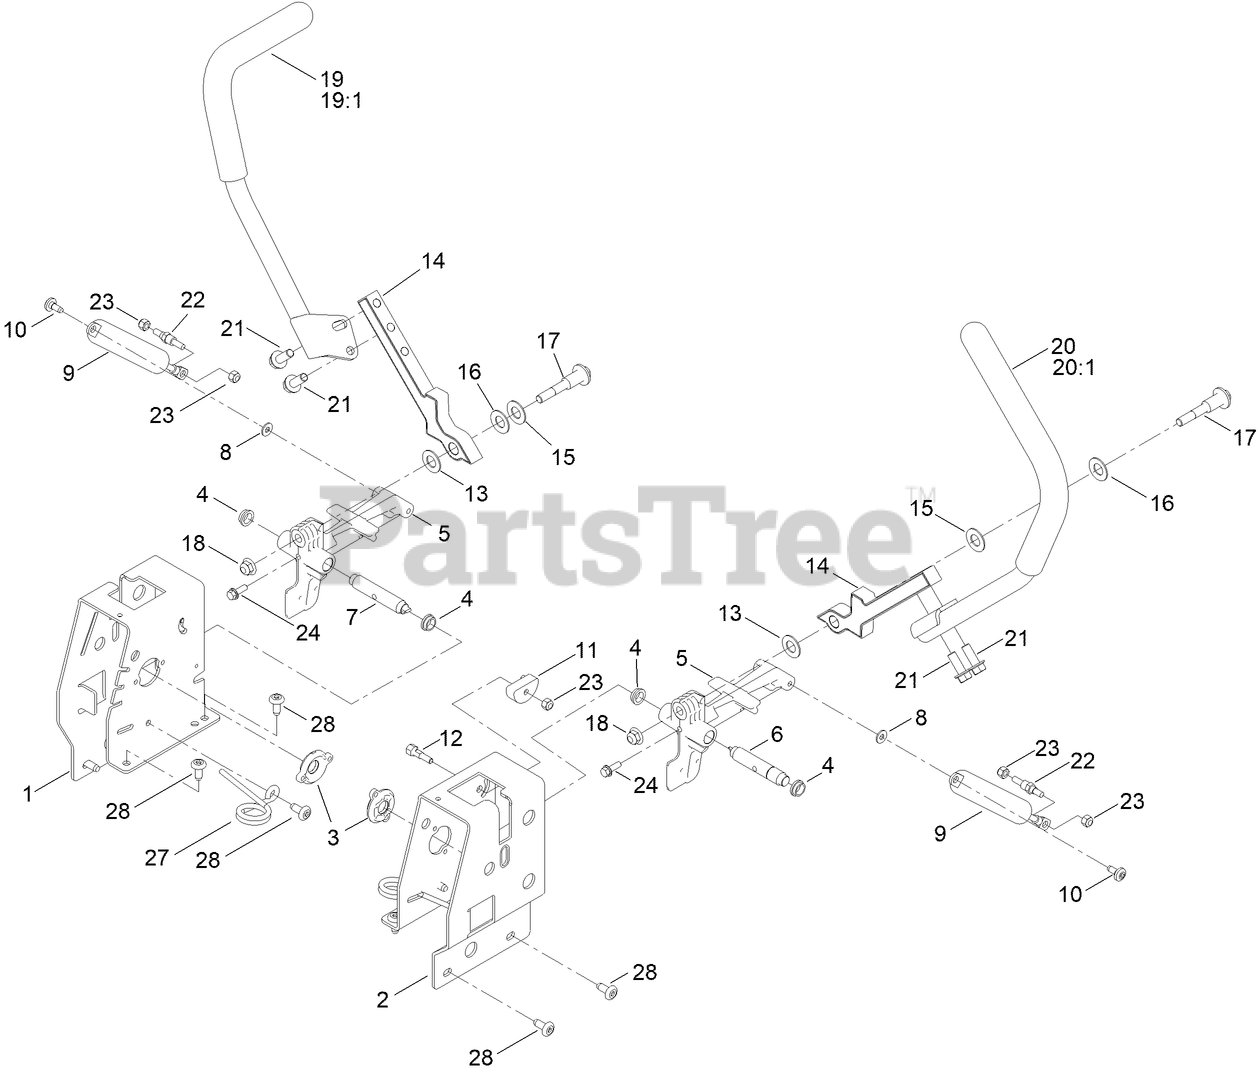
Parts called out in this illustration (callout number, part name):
1	PLATE-CONTROL BOX, RH
2	PLATE-CONTROL BOX, LH
3	SPACER-SENSOR
4	BUSHING-FLANGE
5	ARM-ACTUATOR
6	PIN-LEVER PIVOT, LH
7	PIN-LEVER PIVOT, RH
8	WASHER
9	DAMPER-NON CAVITATING
10	SCREW-SHOULDER
11	ECCENTRIC
12	BOLT-PIVOT, ECCENTRIC
13	WASHER-NYLON
14	ARM-CONTROL
15	WASHER
16	WASHER-BELLEVILLE
17	BOLT-PIVOT
18	NUT-HF, NI
19	HANDLE-CONTROL, RH
20	HANDLE-CONTROL, LH
21	SCREW-HHF
22	STUD-DAMPER
23	NUT-HEX
24	SCREW-HHF
27	SPRING-TORSION
